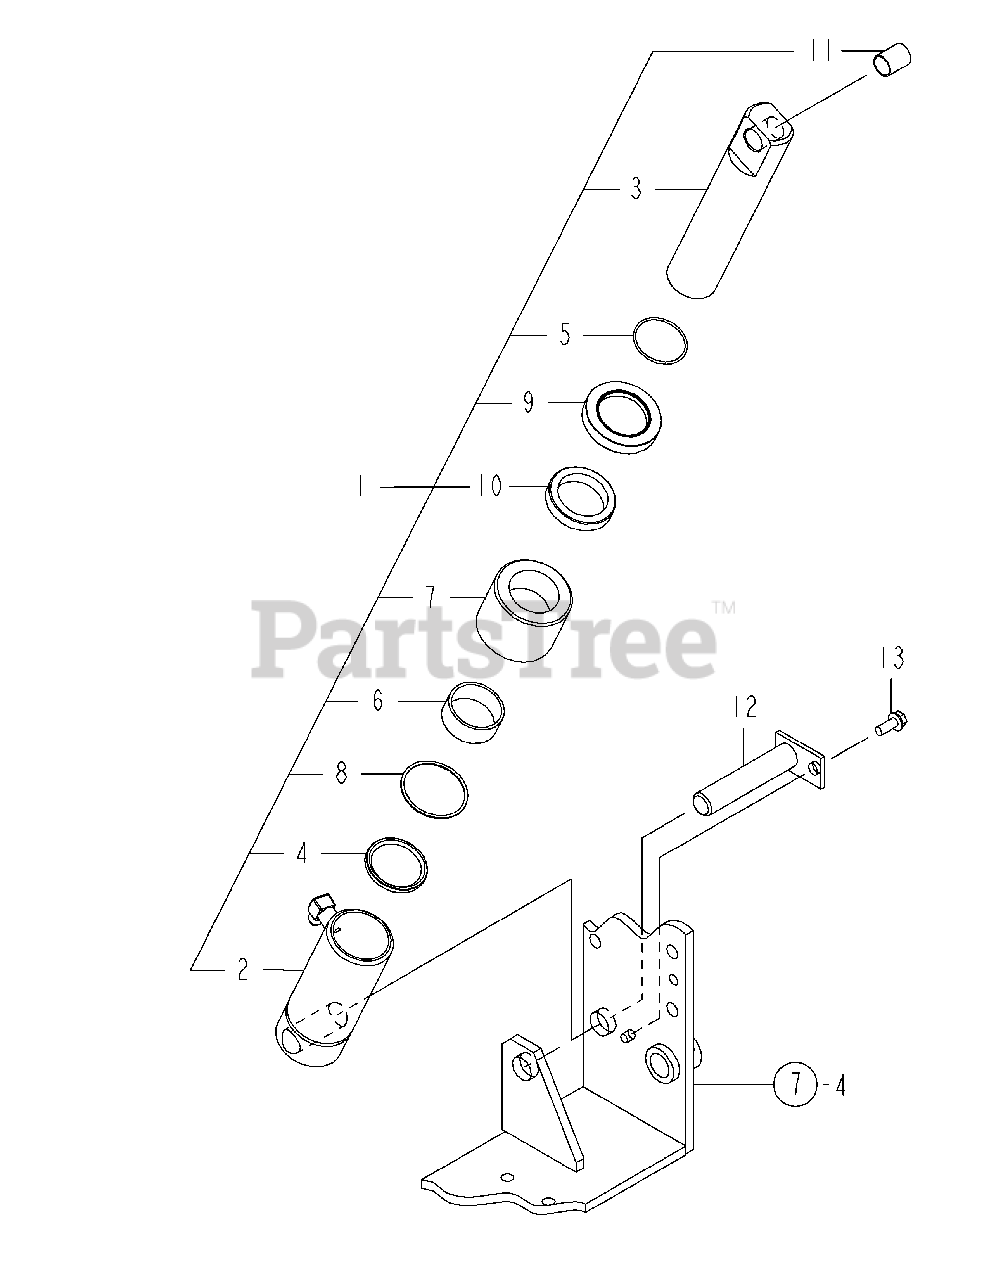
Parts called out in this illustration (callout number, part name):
1	CYLINDER ASSY, HYD.
3	ROD
11	BEARING, 18 X 25
12	PIN CMP (CYLINDER
